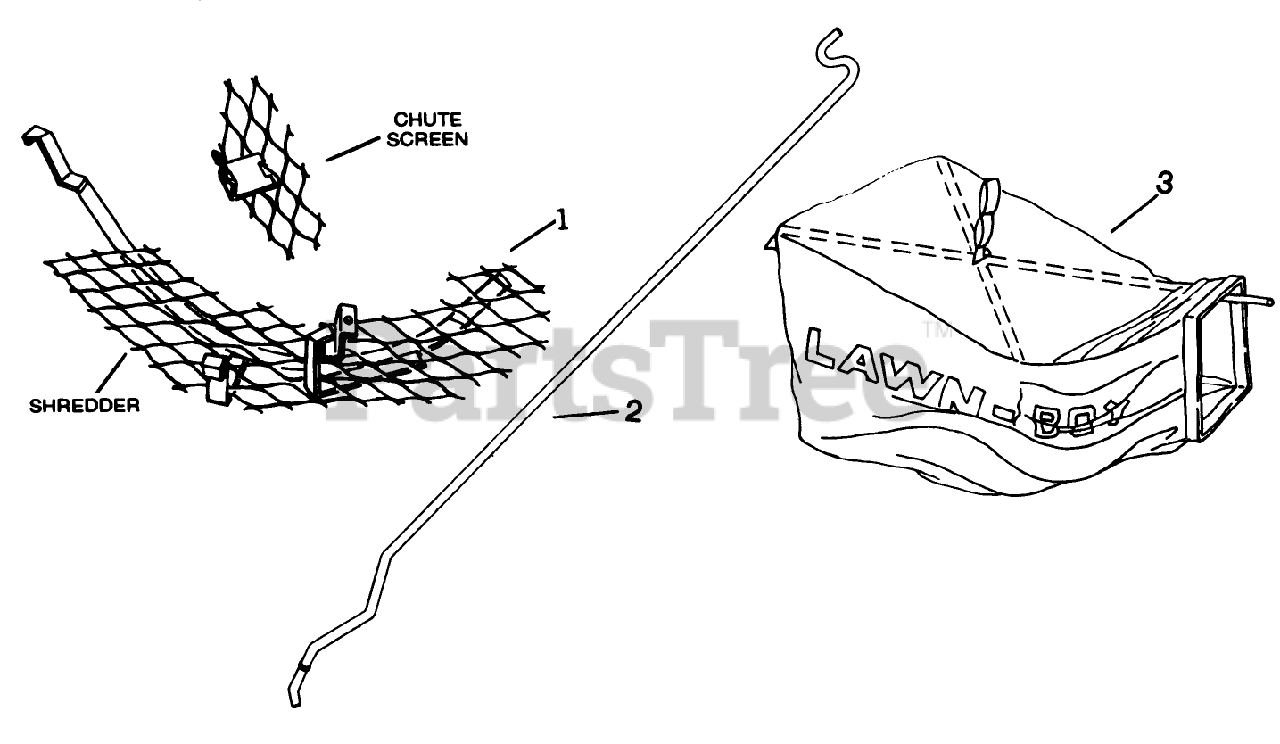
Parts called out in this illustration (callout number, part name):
1	21" Leaf Shredder Kit
2	ROD GRASSBAG
3	Leaf Bag
